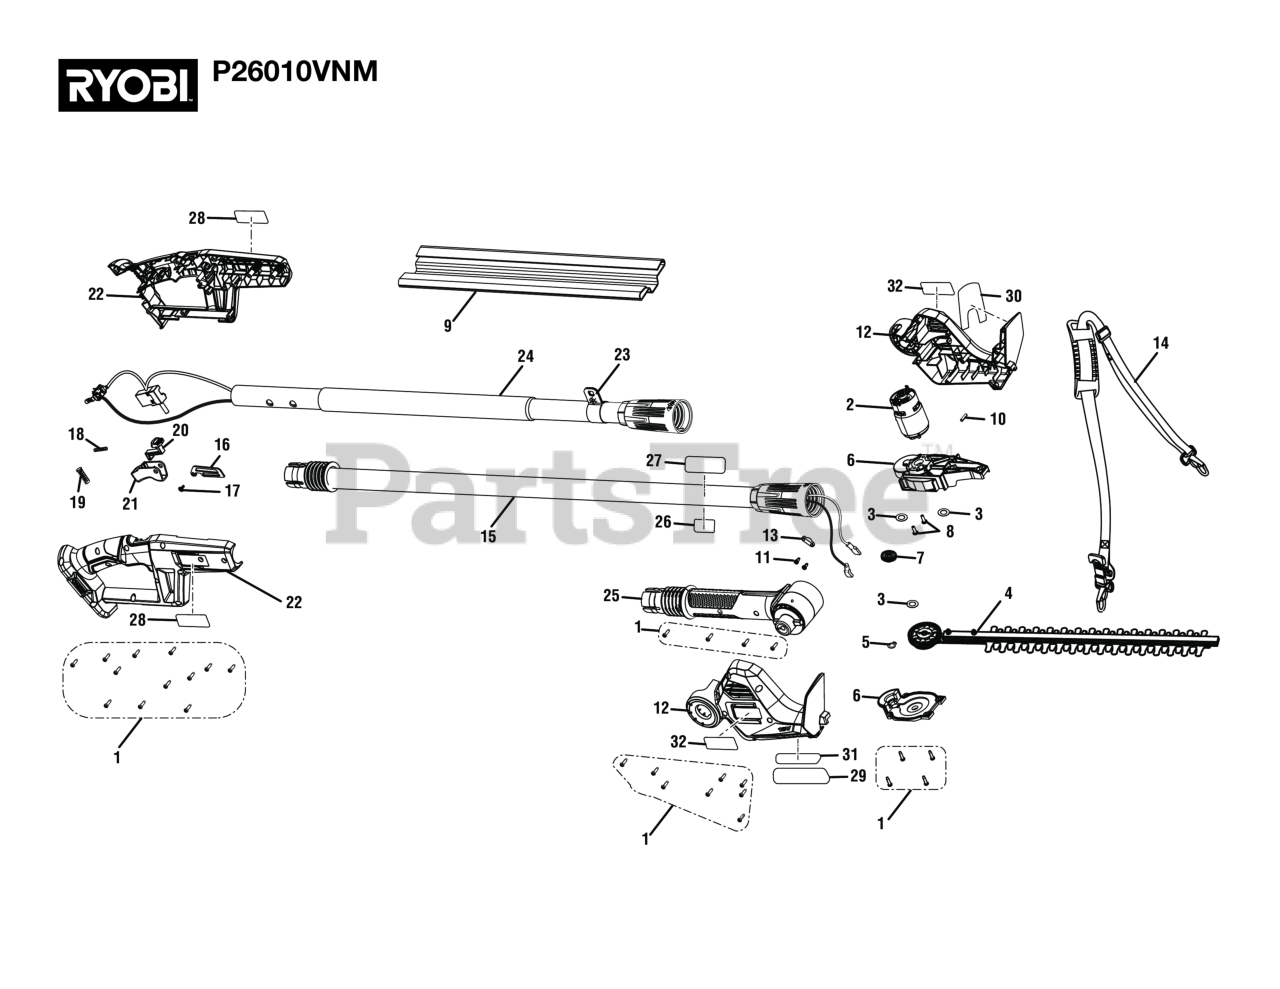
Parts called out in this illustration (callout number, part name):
1	Screw (M4 x 14 mm, T15 Torx Pan Hd.))
2	Motor and Pinion Assembly
3	Washer (M6, ID6.2 x 11OD x 0.3t)
4	Blade Assembly
5	RETAINING RING (EXTERNAL)
6	Gear Box W/Cover Asembly
7	Center Gear
8	Screw w/Tooth Washer (M4 x 12 mm, Pan Hd.)
10	Spring Pin (Small)
11	Screw (M4 x 8 mm, T15 Torx Pan Hd.)
12	Motor Housing Assembly (Inc. Key Nos. 29-32)
13	Cord Clamp
14	Harness Assembly
15	Middle Pole Assembly (Inc. Key Nos. 26-27)
16	Strap Hanger
17	Screw (M3 x 8 mm)
18	Compression Spring (Trigger Lock)
19	Compression Spring
21	Rear Trigger
22	Rear Handle Assembly (Inc. Key No. 28)
23	Clamp Assembly
24	Lower Pole Assembly
25	Pole Hedge Trimmer Handle
27	Warning Icon Label
28	Handle Logo Label
29	Data Label
30	Icon Warning Danger Label (EN/FR)
31	Warning Label (SP)
32	Logo Label
